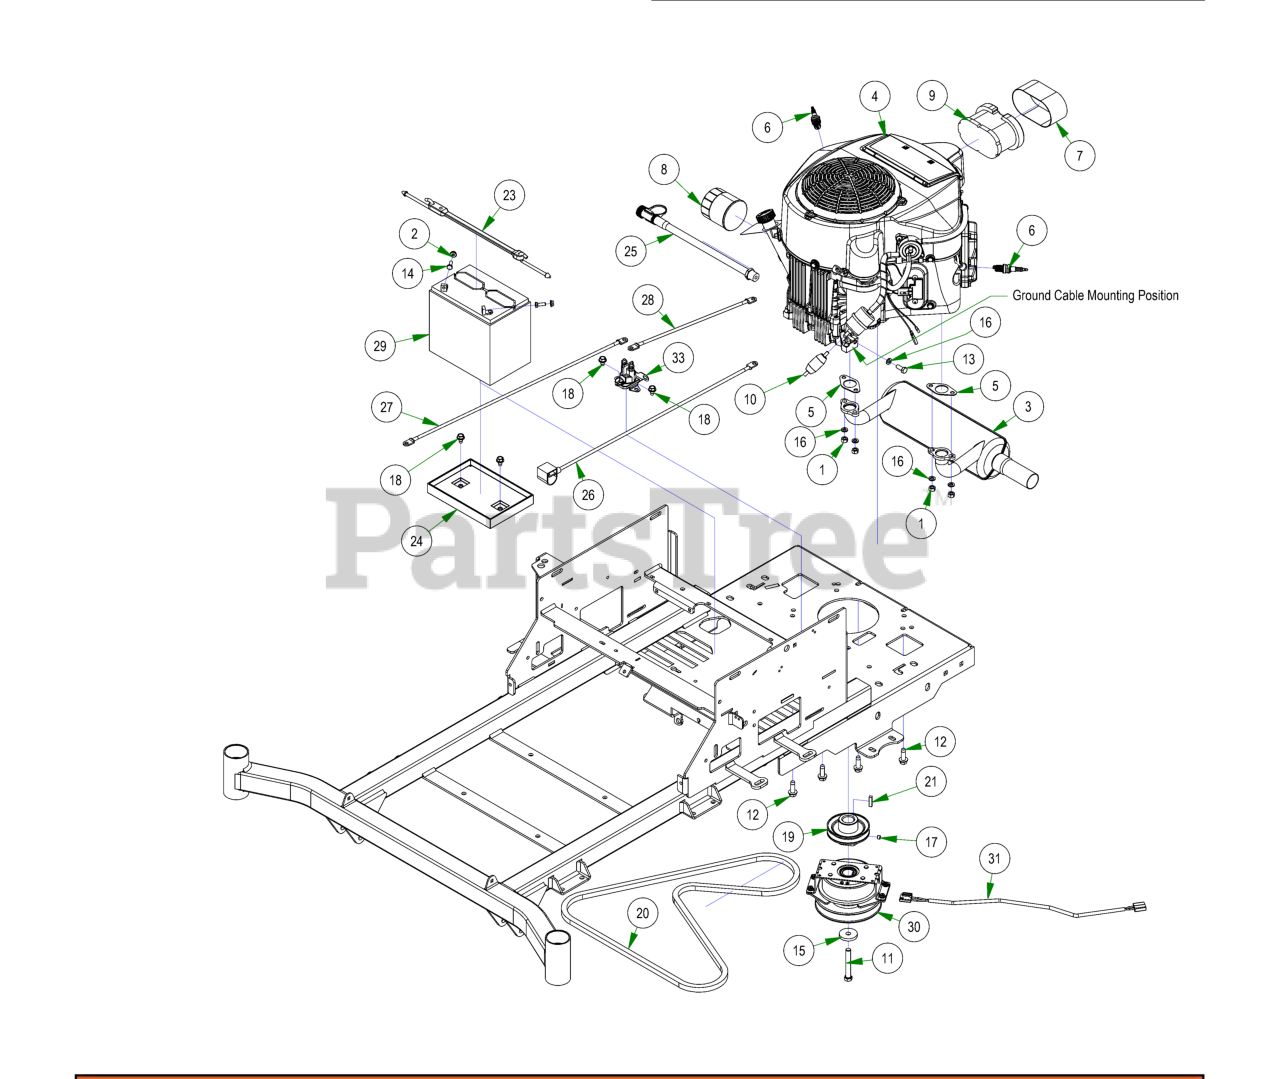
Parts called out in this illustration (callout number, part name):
1	M8-1.25 DIN 934 HEX NUT (CL.8) ZINC
2	1/4-20 HEX SERRATED FLANGE NUT HARD/ZINC
3	Kawasaki Muffler 1251
4	Kawasaki FR691 29.5HP
5	Exhaust Gasket
6	Spark Plug - Kawasaki
7	Air Filter Pre-Cleaner for KAW
8	22-26 Kaw Oil Filter FR Engine
9	Kawasaki Air Filter
10	Universal Inline Fuel Filter
11	7/16-20x3” Hex Bolt GR 8 W/ Patch
12	3/8-16 X 1-1/8 HEX WASHER UNSLOT SERRATED (TRI-LOB) TRS ZINC YELLOW
13	M8-1.25 X 20MM DIN 933 HEX TAP BOLT (CL 8.8) ZINC
14	1/4-20 X 3/4 HEX CAP SCREW (GR.5) ZINC
15	CLUTCH WASHER
16	5/16 SPLIT LOCKWASHER ZINC
17	5/16-24 X 1/4 SOCKET SET SCREW (CUP PT) PLAIN
18	5/16-18 X 1/2 HWH unslot (F) tcs zinc
19	3-3/4" Motor Pulley
21	1/4 X 1 SQ MACHINERY KEY 1018 STL PLN
22	2023 Battery Hold Down Assembly
23	2023 Rubber Battery Hold Down Strap
24	Battery Tray
25	Kawasaki Oil Drain
26	24 inch Black Cable – MZ/ZT
27	24" Red Battery Cable
28	12 in red battery cable
29	SP-35 Battery
31	Clutch Pigtail
32	2024 MZ-Avenger 54-60 Frame
